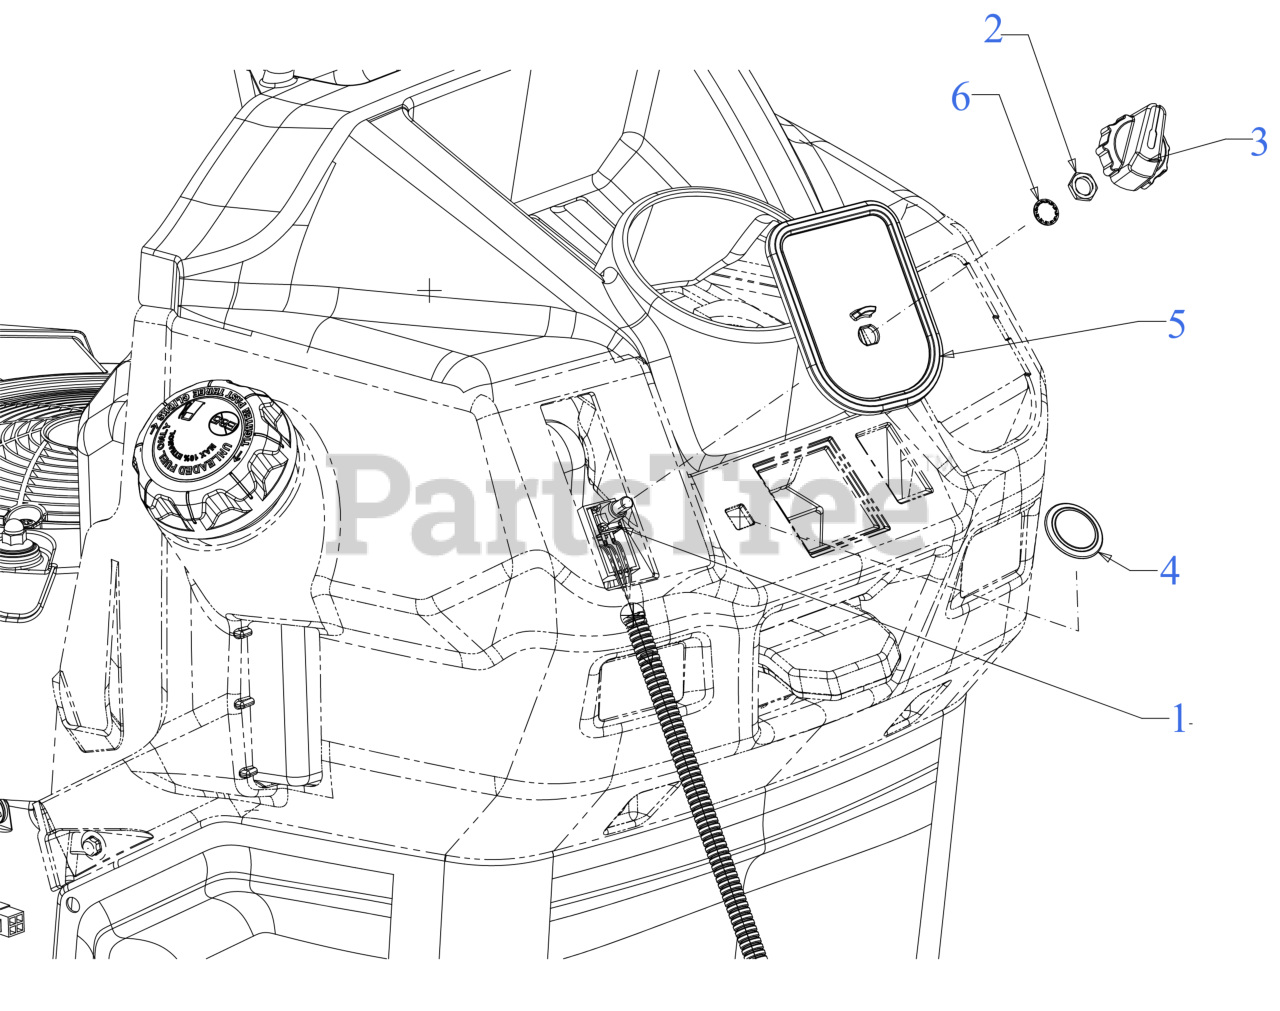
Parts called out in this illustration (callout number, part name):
1	POTENTIOMETER
2	HEX JAM NUT 3/8-32 GR5
3	CONTROL KNOB
4	CHOKE PLUG
5	DASH COVER PLATE
6	INTERNAL TOOTH LOCK WASHER 3/8
